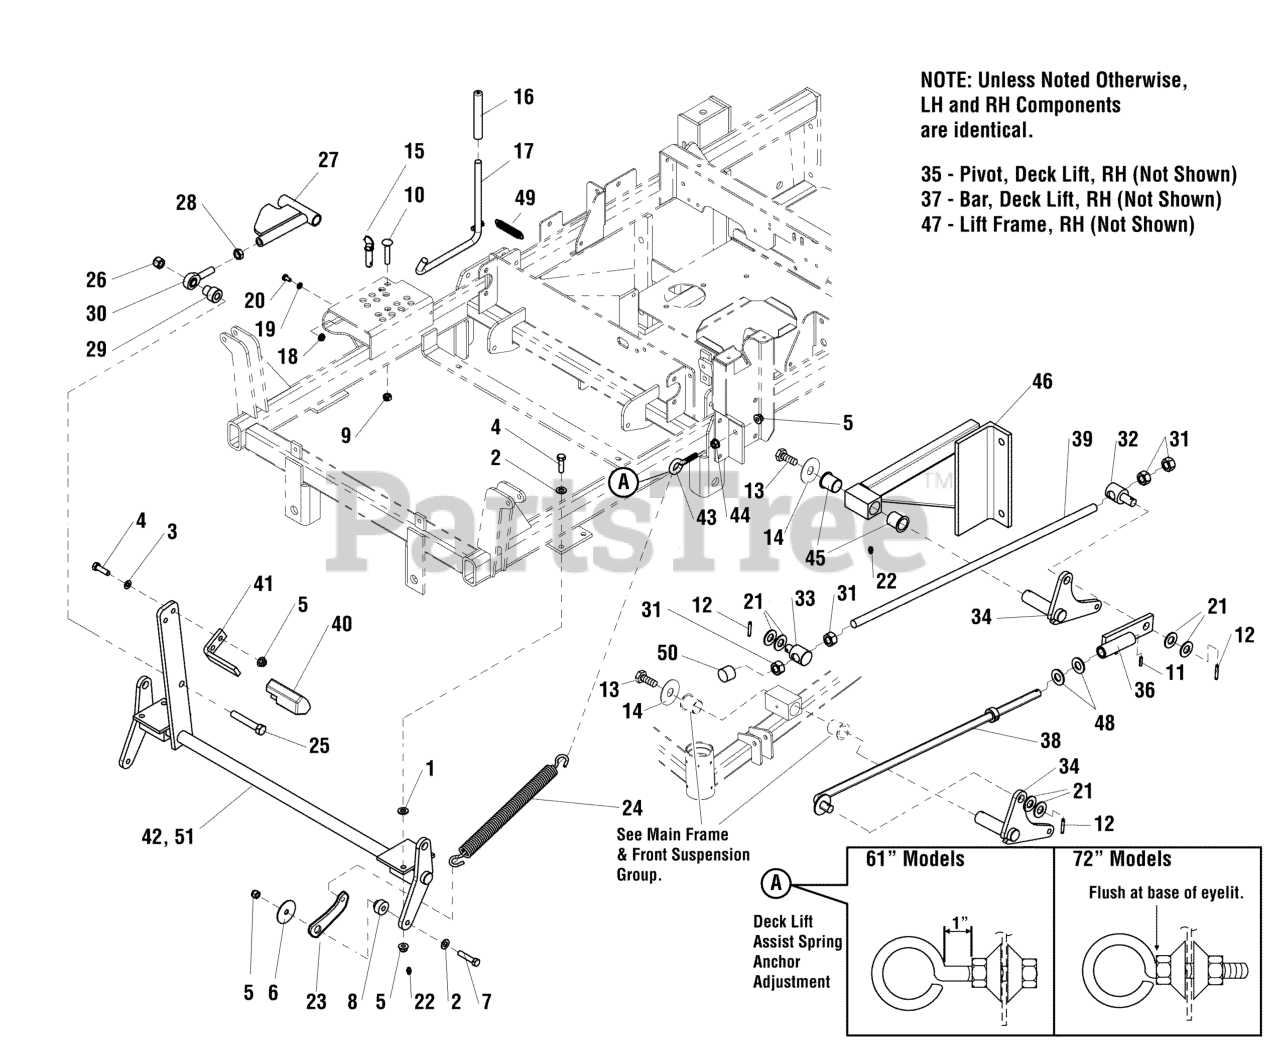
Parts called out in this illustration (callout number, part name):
1	WASHER, 3/8" GD.9 FLAT
2	WASHER, 3/8 SAE
3	WASHER, 5/16" SAE
4	BOLT, 3/8-16 X 1-1/4" GD5 CZ
5	NUT, 3/8-16 HEX NYLOCK FLANGE
6	WASHER, 2.00 X .390 X .135
7	BOLT, 3/8-16 X 2, GD5, CZ
8	BUSHING, DECK PIVOT
9	NUT, 3/8-16 HEX SIDE LOCK
10	BOLT, 3/8-16 X 2", CARRIAGE
11	PIN, ROLL, 3/16 X 1" PLAIN
12	PIN, 3/16" X 1-1/4" SPRING
13	BOLT, 3/8-16 X 3/4, PLT W/PATCH
14	WASHER, .390 X 1.50 X.109 YZ
15	PIN, HITCH, 1/2 X 2.00 OAL, YP
16	GRIP, FOAM
17	WELD, DECK LIFT CONTROL, IS3000 - BLK
18	NUT, 1/4-20 HEX SERR. FLANGE
19	WASHER, 1/4 SAE
20	BOLT, 1/4-20 X 3/4" GD5 YZ
21	WASHER, SHIM, 5/8" X 18GA. YZ
22	GREASE FITTING, 1/4-28 STRAIGHT
23	LINK, SPRING
24	SPRING, DECK LIFT ASSIST
25	BOLT, 1/2-13 X 3-1/2, HEX HD, GD5, CZ (SV)
26	NUT, 1/2-13 HEX NYLON LOCK
27	WELD, DECK ADJUST LINK - RED
28	NUT, 1/2-20 HEX JAM
29	ADAPTER, CASTER AXLE, CZ
30	BALL JOINT, 1/2-20, MALE
31	NUT, 5/8-11 HEX
32	PIVOT, SPRING ROD
33	PIVOT, SPRING ROD
34	PIVOT,DECK LIFT WELD,LEFT
36	BAR, DECK LIFT WELD. - LH
38	ROD, DECK LIFT ASSEMBLY
39	ROD, DECK ADJUSTMENT
40	PEDAL, Rubber
41	PEDAL, FOOT - BLK
42	WELD, DECK LIFT SHAFT 3000 - RED
43	EYEBOLT, 3/8-16 X 2 1/2"
44	NUT, 3/8-16 HEX SERRATED FLANGE
45	BUSHING, 1.00 X 1.13 X 1.38, PLASTIC
46	WELD, LIFT FRAME, LH
48	WASHER, 5/8" SAE
49	SPRING, EXTENSION
50	CAP, VINYL - .562 X .750 - BLK
51	WELD, DECK LIFT SHAFT 3100 - RED
